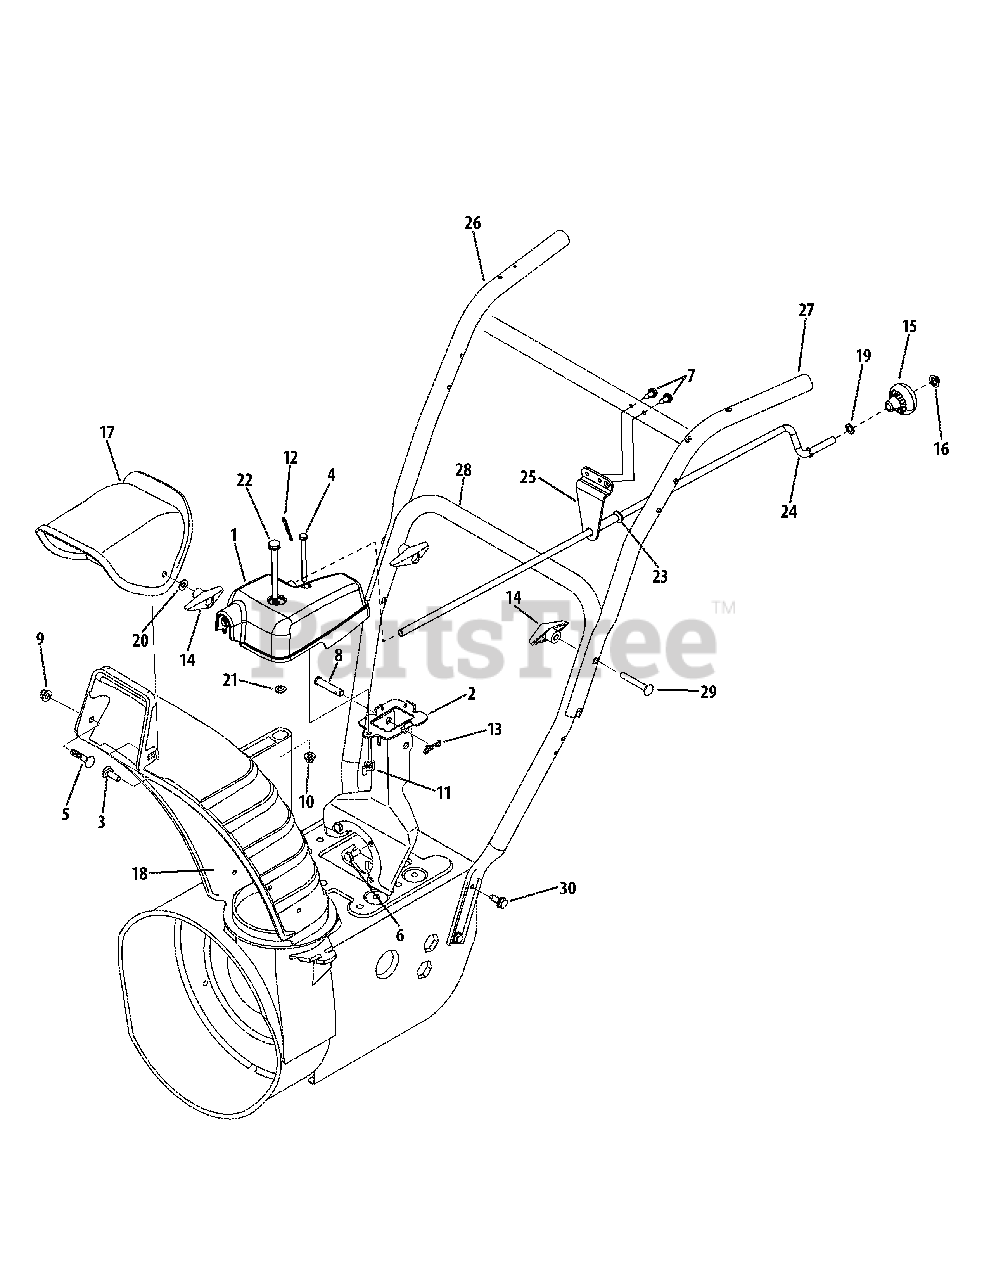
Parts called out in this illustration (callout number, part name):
1	Chute Rotation Gear Box
3	Carriage Bolt, 5/16-18 x .750
4	Hex Screw, 1/4-20 x 3.00
5	Carriage Bolt, 5/16-18 x .750
6	Hex Lock Screw, 5/16-24 x .750
7	Hex Washer Screw, 1/4-20 x .625
8	Clevis Pin, 3/8-1.87
9	Flange Lock Nut, 5/16-18
10	Flange Lock Nut, 1/4-20
11	Wing Nut, 1/4-20
12	Cotter Pin, .08 x 1.42
13	Bow-tie Cotter Pin
14	Wing Knob, 5/16-18
15	Shift Knob, .390
16	Push Cap, 3/8
17	Upper Chute
18	Lower Chute, 5.0
19	Flat Washer, .385 x .62 x .063
20	Flat Washer, .349 x .879 x .063
21	Flat Washer, .25 x .630 x .0515
22	Shoulder Screw, .312 x .5 x 1/4-20
23	Plastic Bushing
29	Carriage Screw, 5/16-18 x 2.25
30	Hex Washer Screw, 5/16-18 x .750
